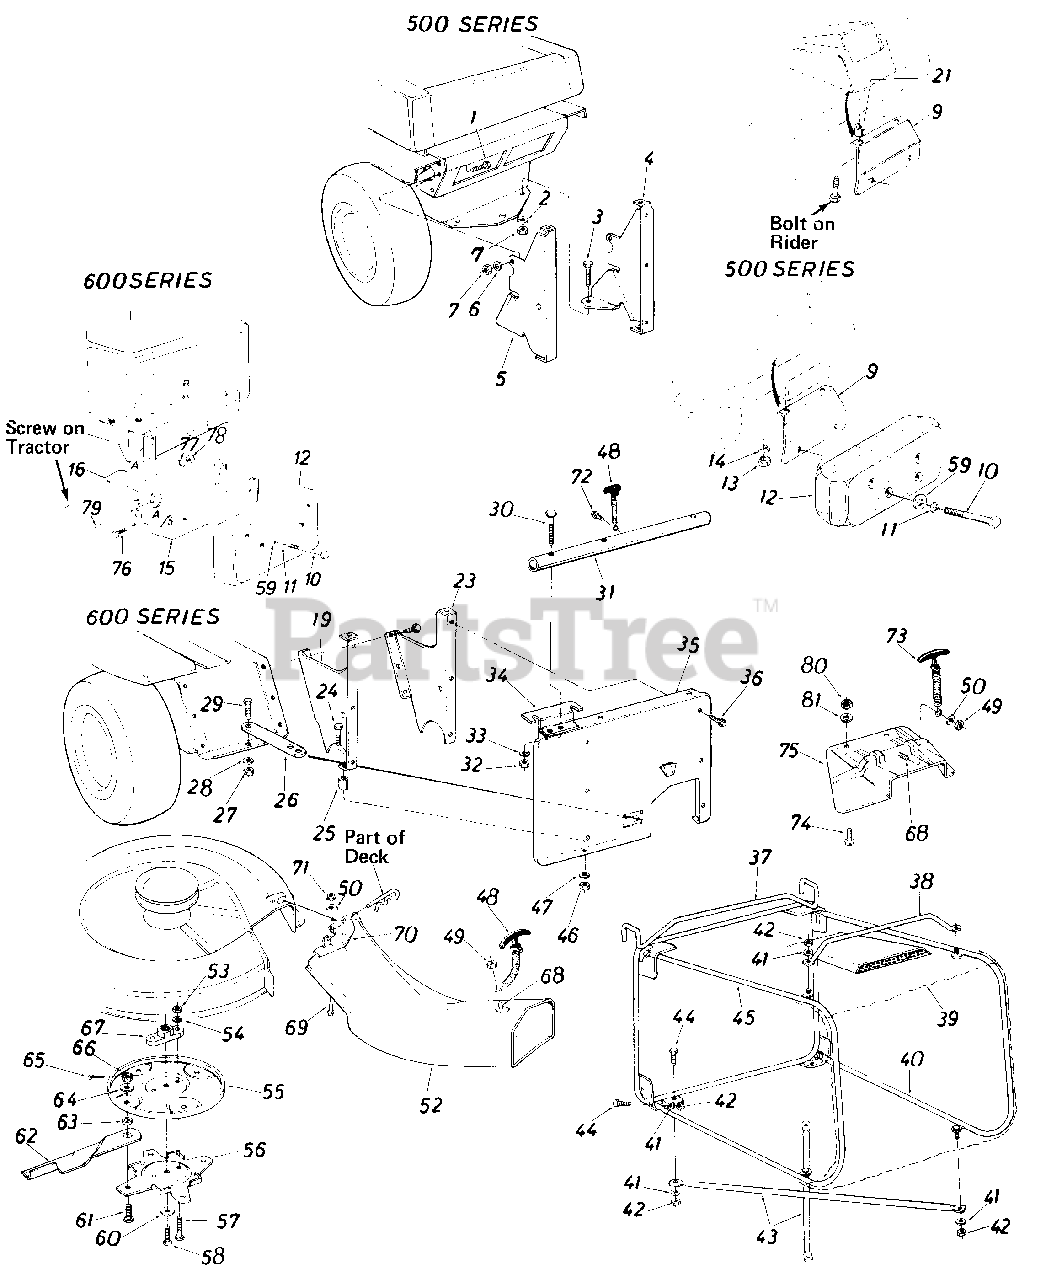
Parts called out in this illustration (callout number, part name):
1	Hex Bolt 5/16-18 x 1.0" Lg.*
2	L.-Wash. 5/16" I.D.*
3	Hex Bolt 5/16-18 x 1.0" Lg.*
4	Catcher Support Brkt - R.H.
5	Catcher Support Brkt - L.H.
6	L.-Wash. 5/16" I.D.*
7	Hex Nut 5/16-18 Thd.*
9	Counterweight Support Brkt. Ass 'y
10	Hex Bolt 3/8-16 x 4.5" Lg.*
11	Belleville Wash. .40" I.D. x .88" O.D.
12	Counterweight 38 Ibs.
13	Hex Nut 5/16-18 Thd.*
14	L.-Wash. 5/16" I.D.*
15	Counterweight Support Brkt. Ass'y.
16	Tie Strap t
19	Catcher Support Brkt. - L.H.
21	Spacer .380" I.D. x 1.0" O.D. x .32" Lg.
23	Catcher Support Brkt. - R.H.
24	Hex Bolt 5/16-18 x 1.50" Lg.*
25	Spacer .380" I.D. x .47" O.D. x 1.0" Lg.
28	L.-Wash. 1/2" I.D.*
29	Hex Bolt 1/2-20 x 1.0" Lg.*
30	Curved Carriage Bolt 5/16-18 x 1.75" Lg.
33	L.-Wash. 5/16" I.D.*
34	Grass Catcher Support Plate
35	Rear Discharge Panel
36	Hex Wash. Hd. Self Tap. Scr. 1/4-20 x .50" Lg.
37	Grass Catcher Frame Ass'y.
42	Hex L.-Nut 1/2-20 Thd
43	Bottom Cross Brace
44	Hex Bolt 1/4-20 x .62" Lg.*
47	L-Wash. 5/16" I.D.
48	Hook Latch Ass'y.
49	Hex L.-Nut 1/4-20 Thd.
50	Fl.-Wash. 1/4" I.D.*
52	R.D. Banana Chute Ass'y.
53	Hex Nut 5/16 24 Thd.*
54	L.-Wash. 5/16" I.D.
55	Upper Blade Disc
58	Hex Bolt 3/8-24 x 1.0" Lg.
59	Fl.-Wash. .39" I.D. x 1.12" O.D.
60	Bell.-Wash. 39" I.D. x 1.38"
61	Shld. Bolt. .50" Dia. x .360 Spec.
62	30" Blade Tip
63	Spacer .505" I.D. x .75" O.D. x 1.25" Lg.
64	Fl.-Wash. .50" I.D. x 1.25" O.D.
65	Cotter Pin 3/32" Dia. x 1.0" Lg.*
66	Hex Slotted Nut 1/2-2 Thd.
67	Blade Adapter
68	Hex Bolt 1/4-20 x -50" Lg-*
69	Truss Mach. Scr. 1/4-20 x .50" Lg.*
72	Hex AB Tap Scr. 1/4 x .62" Lg.
73	Hook Latch Ass'y. 7" Lg.
74	Truss Mach. Scr. 1/4-20 x 50" Lg.*
75	R D Chute Extension
76	Hex Bolt 7/16-20 x 1.0" Lg.*
77	L.-Wash. 7/16" I.D.*
78	Hex Nut 7/16-20 Thd.*
79	Self-Tap- Scr. 5/16-18 x 1.0" Lg.
80	Hex L.-Nut 1/4-20 Thd.
81	Fl.-Wash. .281" I.D. x .50" O.D. x .063
